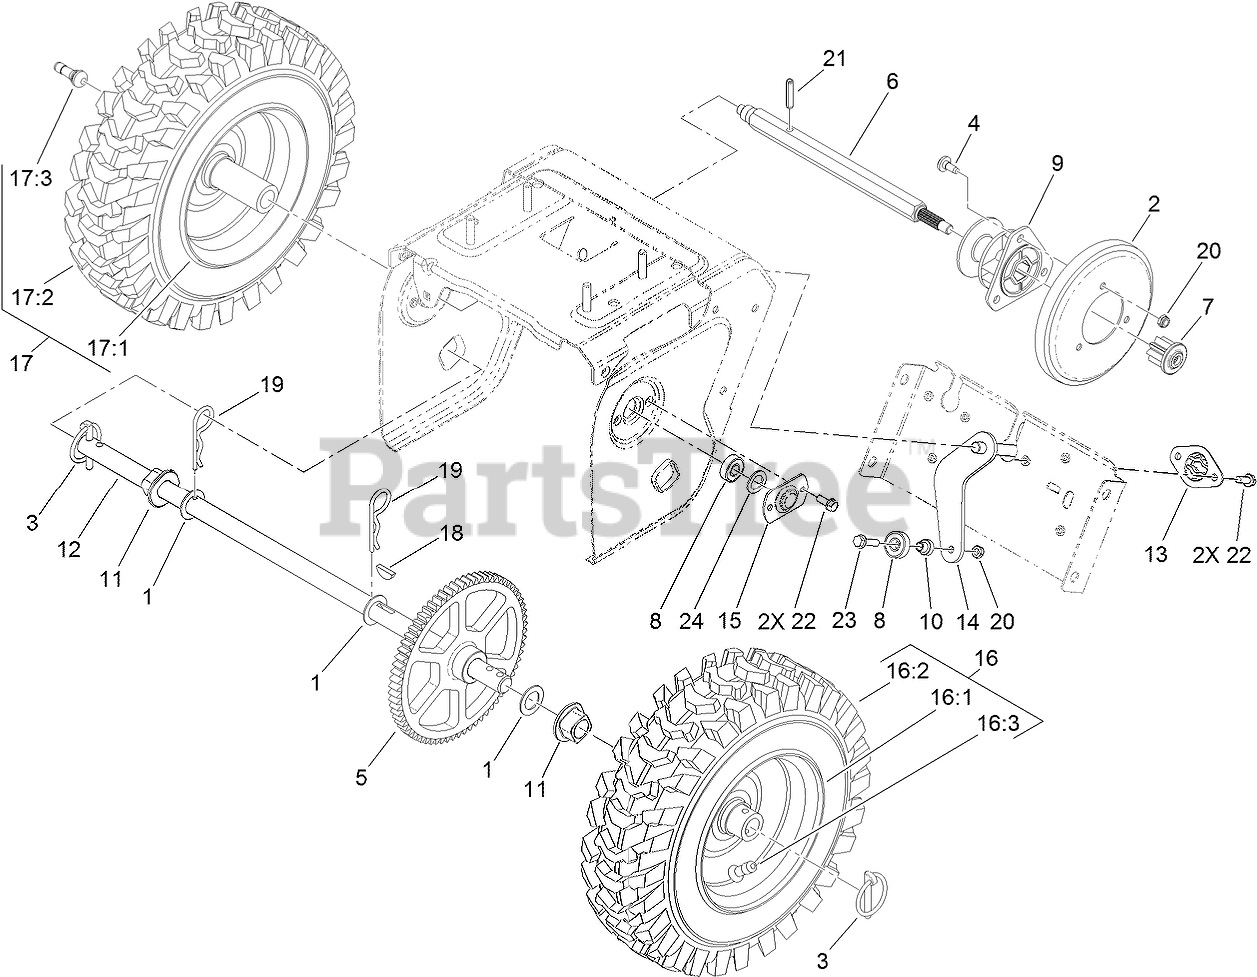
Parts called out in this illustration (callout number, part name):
1	WASHER-THRUST
2	WHEEL-FRICTION
3	KLIK PIN ASM
4	SCREW-SHOULDER
5	GEAR-AXLE
6	SHAFT-HEX
7	GEAR-PINION, 8 TOOTH
8	BEARING-BALL
9	TRUNNION
10	SPACER-PLATE, SHIFT
11	BUSHING-AXLE
13	RETAINER-PLATE, SHIFT
14	SHIFT PLATE ASM
15	RETAINER-BEARING
16	LH WHEEL AND TIRE ASM
16:3	STEM-VALVE
17	RH WHEEL AND TIRE ASM
17:3	STEM-VALVE
18	KEY-WOODRUFF
19	PIN-HAIR
20	NUT-LOCK, NI
21	PIN-ROLL, SLOTTED
22	SCREW-HWH
23	SCREW-HWHTF
24	WASHER-RUBBER
